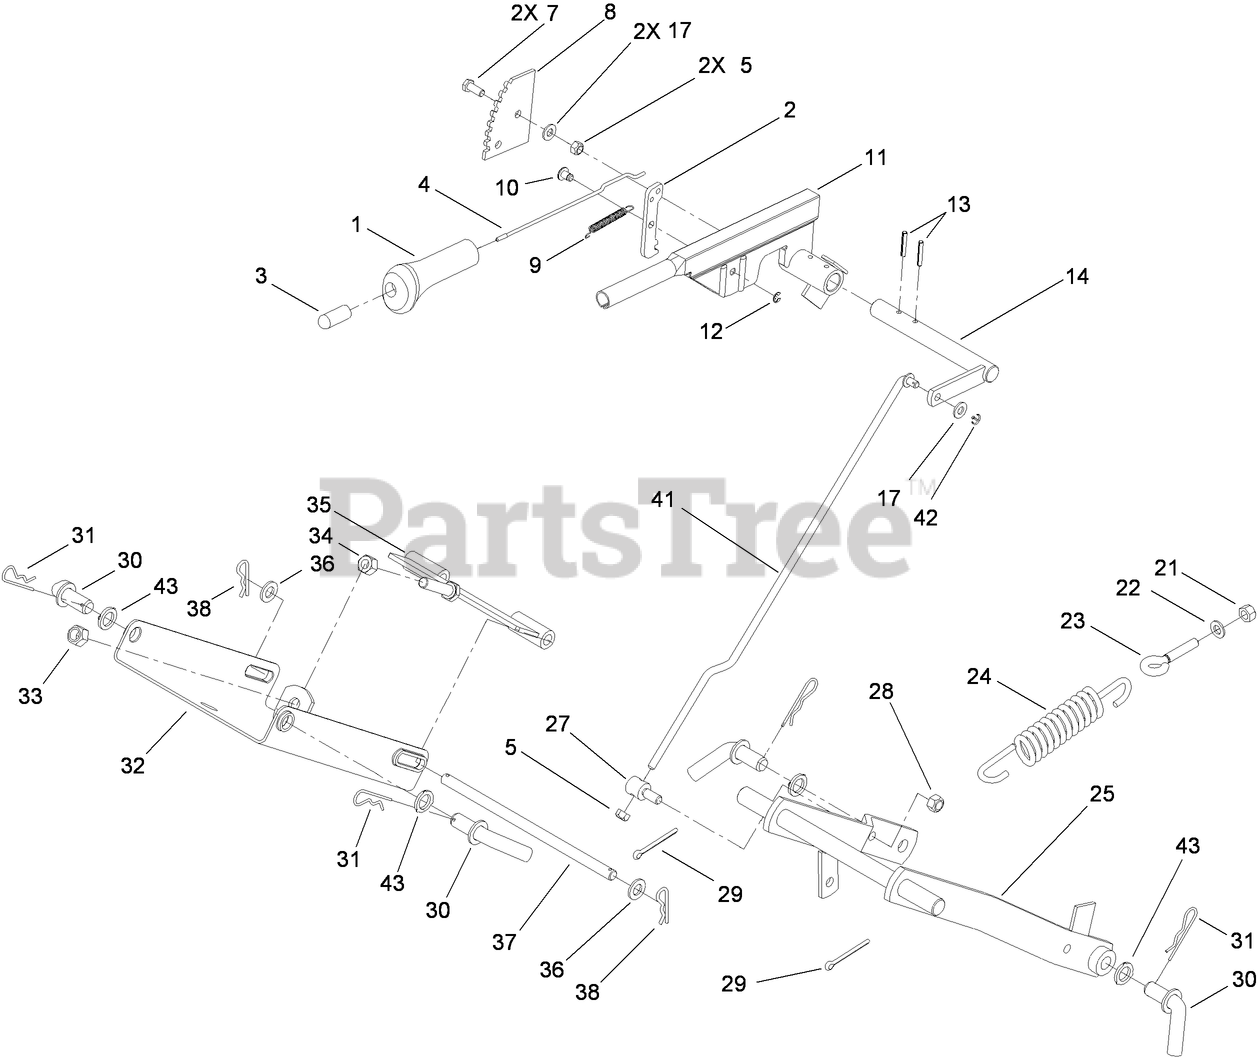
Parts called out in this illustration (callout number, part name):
1	GRIP-HANDLE
2	RATCHET-PLATE, PIVOT
3	BUTTON-PLUNGER
4	ROD-CONNECTION
5	NUT-LOCK, NI
7	SCREW-HH
8	GEAR-SEGMENT, DECK LIFT
9	SPRING
10	PIN-LEVER, ARM
11	LEVER-ARM, HEIGHT ADJ.
12	CLIP-PIN
13	PIN-SPRING
14	SHAFT-LIFT, DECK
17	WASHER-PLAIN
21	NUT-LOCK, NI
22	WASHER-FLAT
23	BOLT-EYE
24	SPRING-LIFT
25	PIVOT ARM ASM
27	PIN-LIFTING
28	NUT-LOCK, NI
29	PIN-COTTER
30	PIN-BENT
31	PIN-HAIR
32	SUSPENSION-MOWER DECK, FRONT
33	NUT-HEX
34	NUT-HEX
35	HOLDER-FRONT
36	WASHER-FLAT
38	PIN-HAIR
41	ROD-HEIGHT, ADJ.
42	PIN-COTTER
43	Washer-Hose
